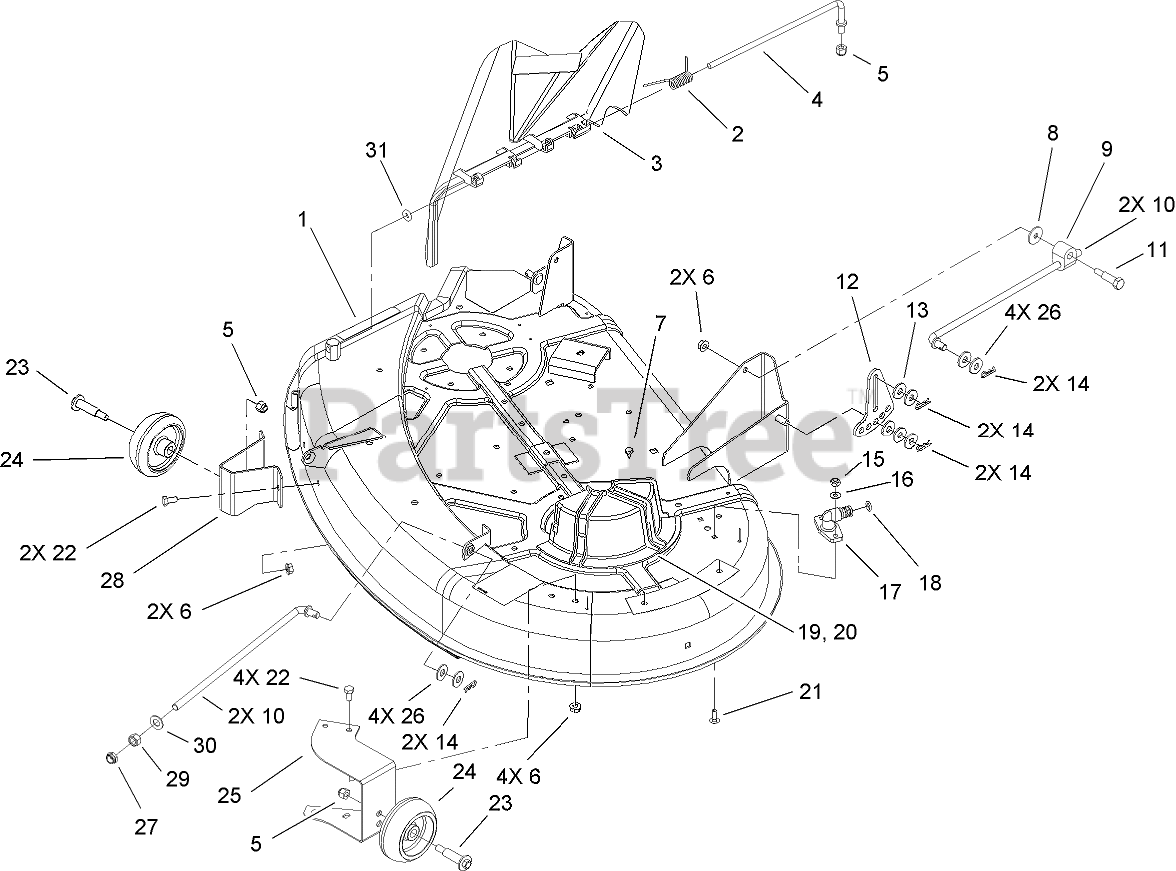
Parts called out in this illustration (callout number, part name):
1	38 INCH DECK ASM
2	SPRING
3	DEFLECTOR ASM
4	ROD-PIVOT
5	NUT-LOCK, NI
6	NUT-HF
7	SCREW-HWHTF
8	WASHER-PIVOT
9	TRUNNION-HOC
10	ROD-HANGER
11	SCREW-SHOULDER, HH
12	LINK-ADJUSTING, HOC
13	WASHER-HARDENED
14	PIN-HAIR
15	NUT-LOCK, NI
16	WASHER-FLAT
17	FITTING-WASHOUT
18	O-RING
19	GUIDE-BELT, LH
21	BOLT-CARR
22	SCREW-HH
23	SCREW-SHOULDER, HWH
24	WHEEL-GAGE
25	BRACKET-WHEEL, GAGE (FRONT, LH)
26	WASHER-FLAT
27	NUT-LOCK, NI
28	BRACKET-WHEEL, GAGE (FRONT, RH)
29	NUT-HEX
30	WASHER-FLAT
31	O-RING
